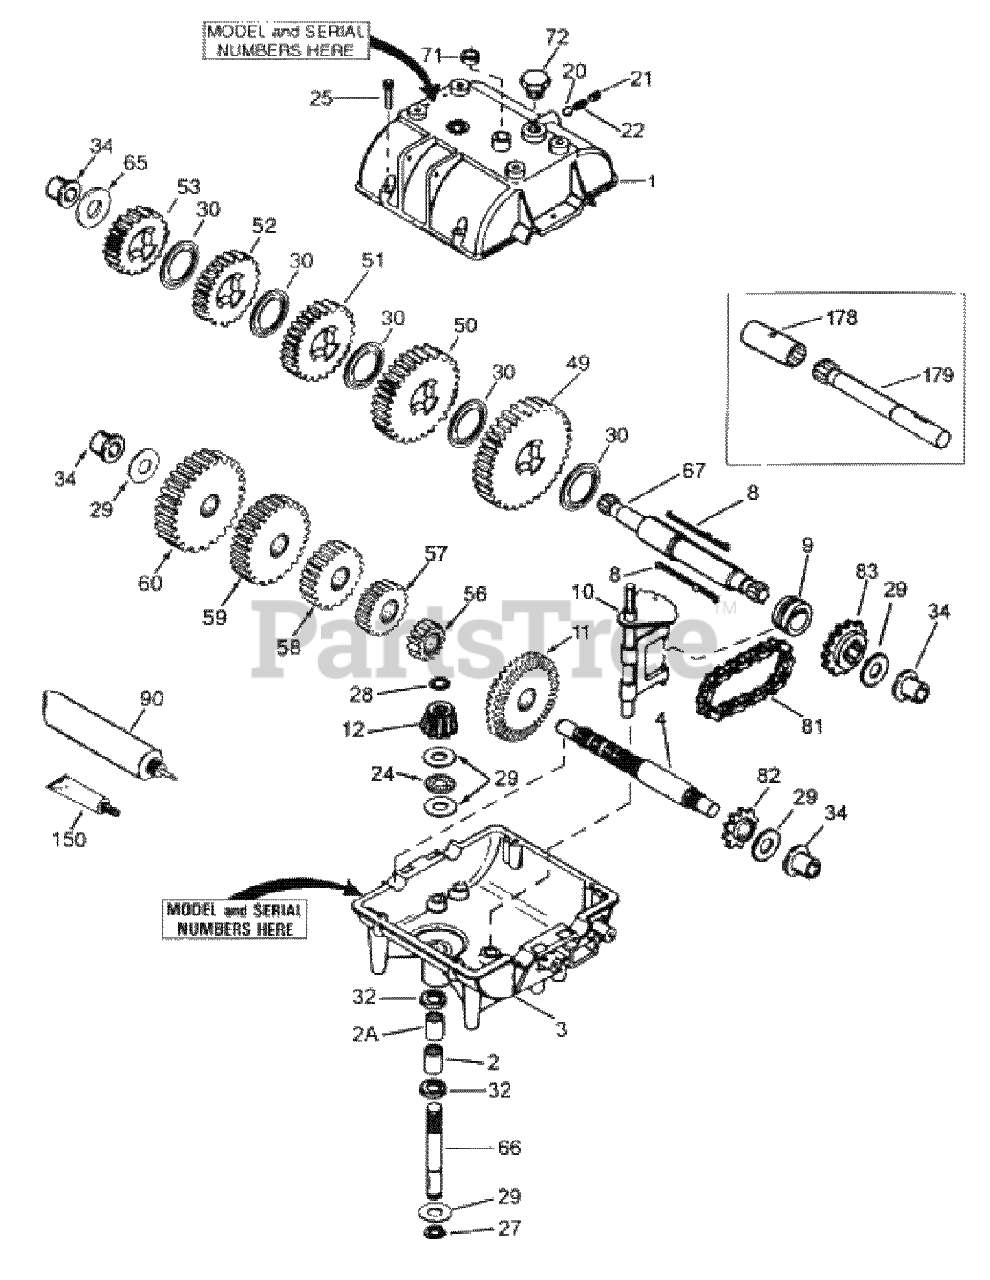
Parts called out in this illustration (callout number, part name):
1	Cover-Transmission
2	Bearing-Needle
2A	Bearing-Needle
3	Case-Transmission
4	Countershaft
9	Collar-Shift
10	Shift Rod Fork
11	Gear-Bevel, 42 teeth
12	Bevel Pinion (14 Teeth-Steel)
20	Ball-Steel
21	Screw-Set
22	Spring
24	Bearing-Thrust
25	Screw
27	Ring-Snap
28	Ring-Retainer
29	Washer
30	Washer
32	O Ring
34	Bushing-Flange
49	Gear-Spur, 37 Teeth
50	Gear-Spur, 35 Teeth
51	Spur Gear (32 Teeth-Steel)
52	Gear-Spur, 30 Teeth
53	Gear-Spur, 25 Teeth
56	Gear-Spur, 12 Teeth
57	Gear-Spur, 15 Teeth
58	Spur Gear (18 Teeth-Steel)
59	Gear-Spur, 20 Teeth
60	Gear-Spur, 25 Teeth
65	Washer
66	Shaft-Input
67	Shifter and Brake Shaft
71	Cut Seal-Square
81	Chain-Roller #41
82	Sprocket-9 Teeth
83	Sprocket-18 Teeth
90	Grease 32 Oz
150	Gasket Eliminator
178	Coupling (Optional)
179	Connector Shaft(Optional)
